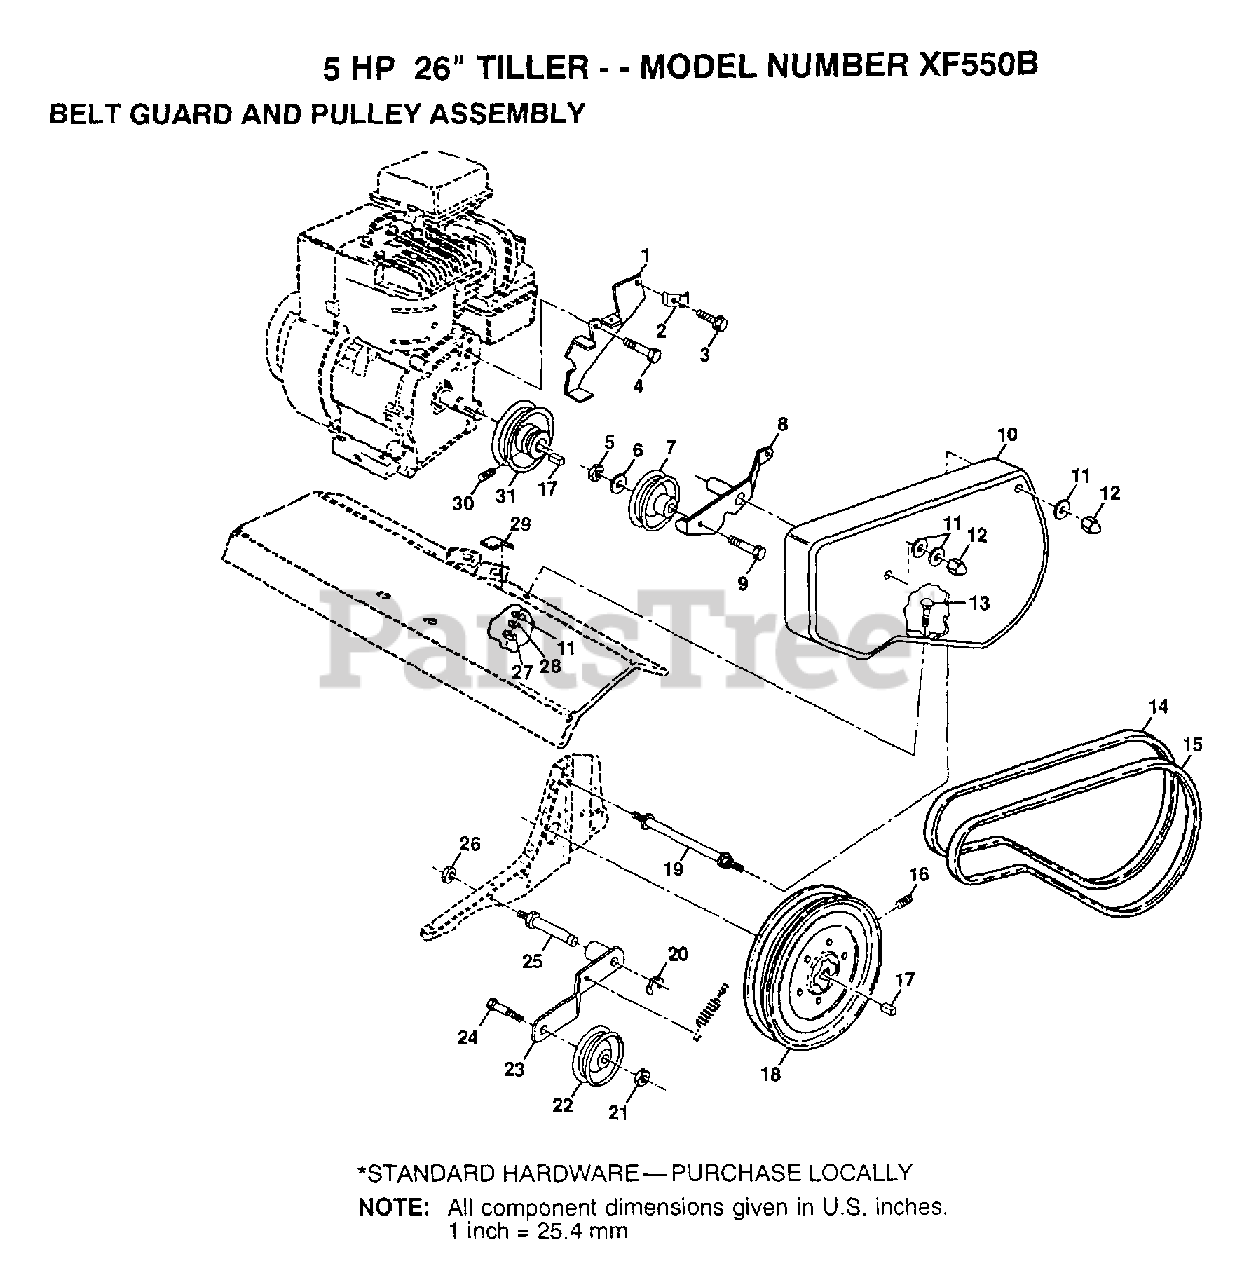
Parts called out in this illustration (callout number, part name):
2	CONDIUT CLIP T
5	NUT.HEX.3/8-16UNC
6	WASHER
7	PULLEY W/SPACER
8	ARM.ASM.REV.IDLER
11	WASHER
12	NUT-CAP TI
13	BOLT T
14	BELT-V
16	SET SCREW
17	KEY T
19	BOLT TI
20	KLIP RING TI
21	NUT
23	IDLER ARM TI
25	SHAFT IDLER TI
26	JAM NUT TI
28	LOCKWASHER
29	PAD IDLER TI
30	SET SCREW
31	ENGINE PULLEY TI
